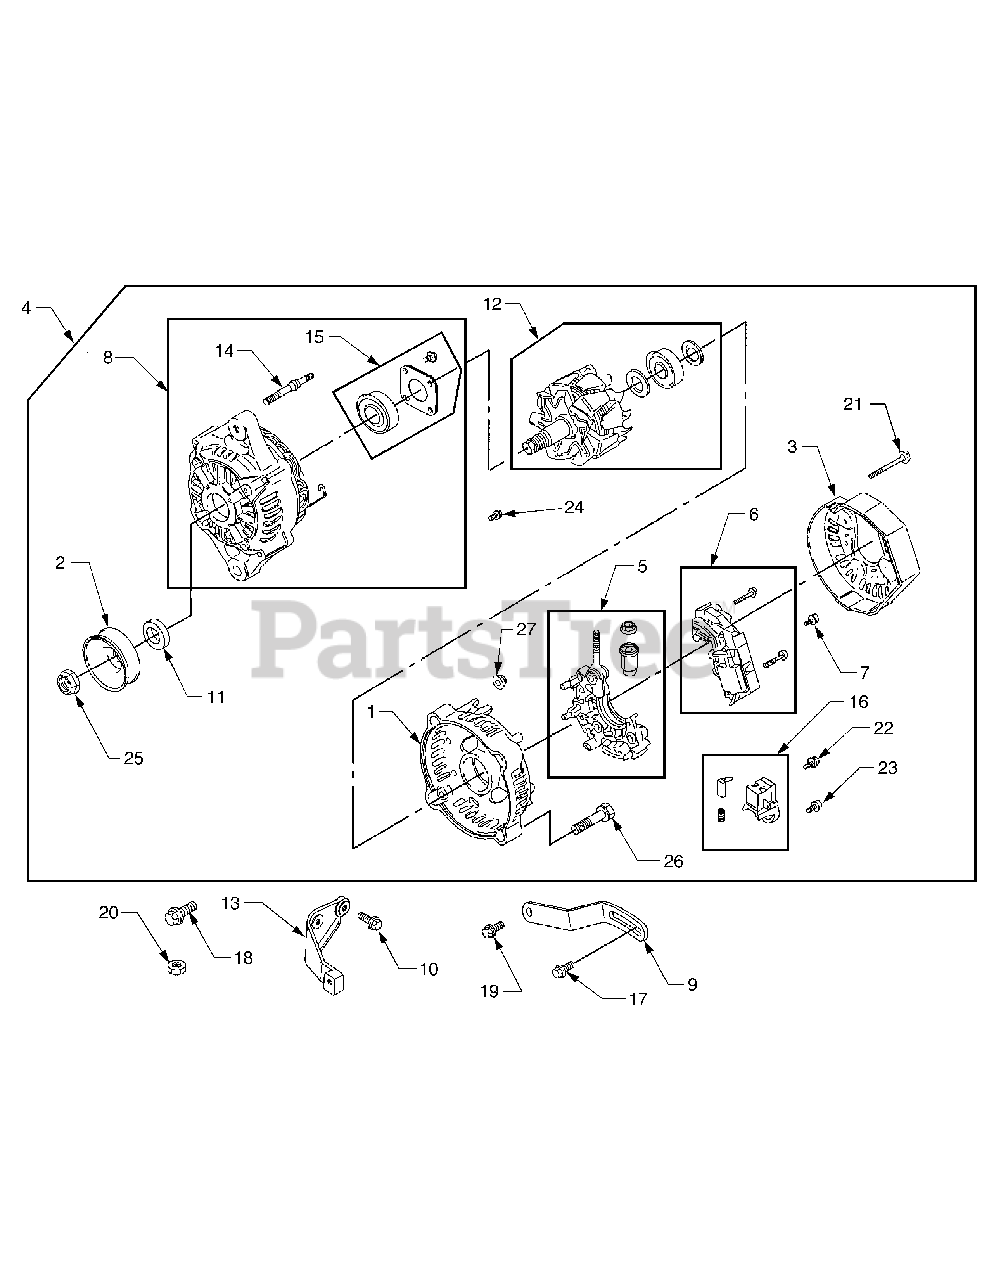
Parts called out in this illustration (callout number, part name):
1	Housing, Brush End
2	Pulley, Alternator
3	Cover, Brush
4	Alternator
7	Screw, Rectifier
8	Housing, Drive End
9	Strap, Adjusting
10	Screw, Support Bracket
11	Spacer, Support Bracket
13	Bracket, Support
14	Stud, Alternator
15	Retainer, Bearing
16	Retainer, Brush
17	Screw, Alternator
18	Screw, Alternator
19	Screw, Adjusting Strap
20	Nut, Alternator
21	Screw, Brush Cover
22	Screw, Brush Retainer
23	Screw, Brush Retainer
24	Screw, Ground Terminal
25	Nut, Alternator Pulley
26	Screw, Brush End Housing
27	Nut, Brush End Housing
